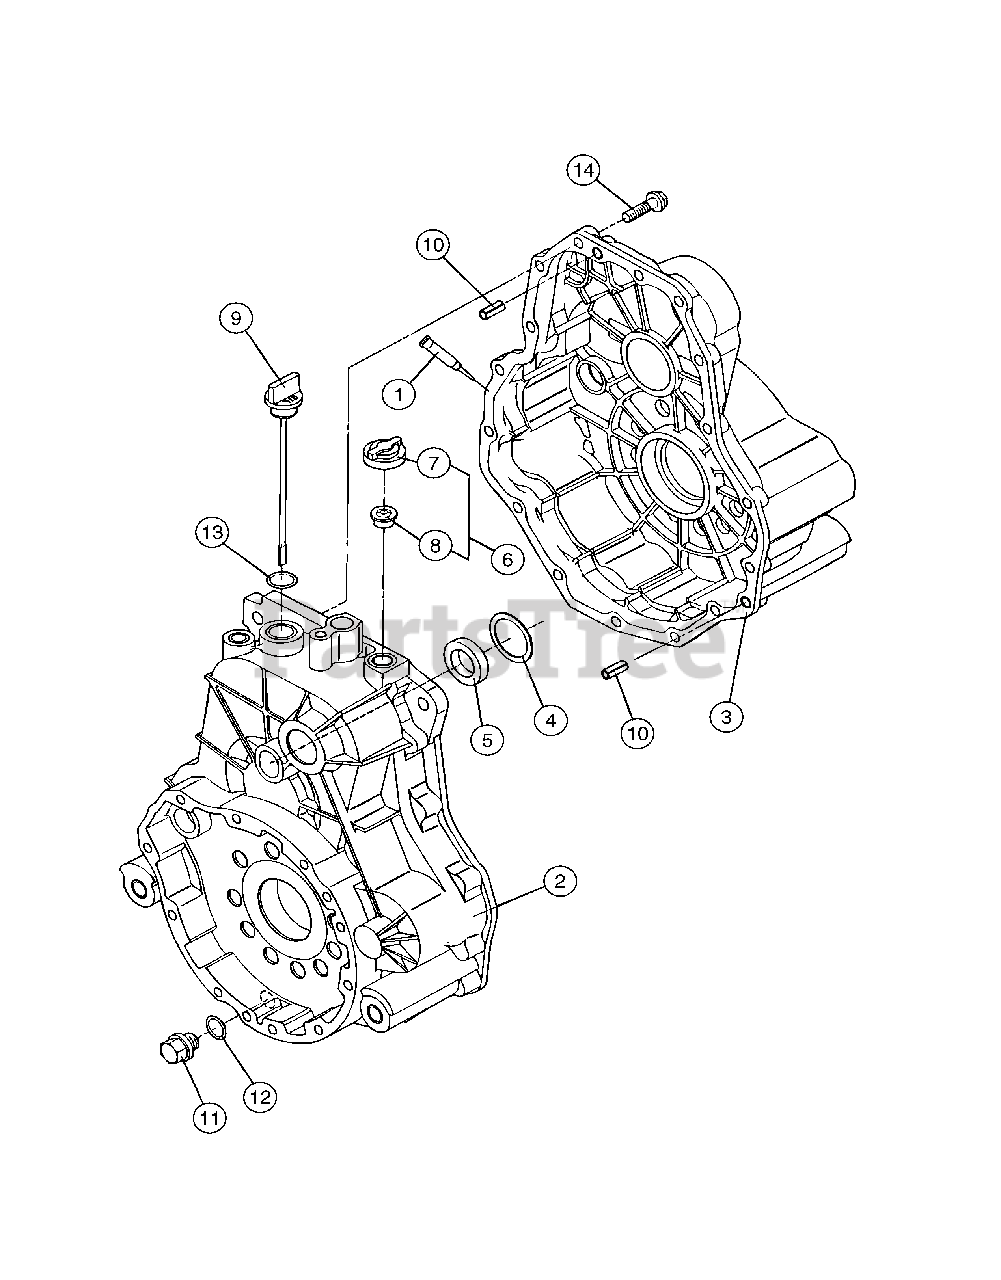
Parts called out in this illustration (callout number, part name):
1	Sealant
2	Housing, Transaxle, Left
3	Housing, Transaxle, Right
4	Washer, 36 x 45.5 x 1.2
5	Seal, TC 30 40 8
6	Vent Valve
7	Cap, Vent Valve
8	Body, Vent Valve
10	Pin, 8 x 20
11	Plug, 14
12	Packing, P 16
13	Packing, P 18
14	Bolt, 28 x 10 x 9
